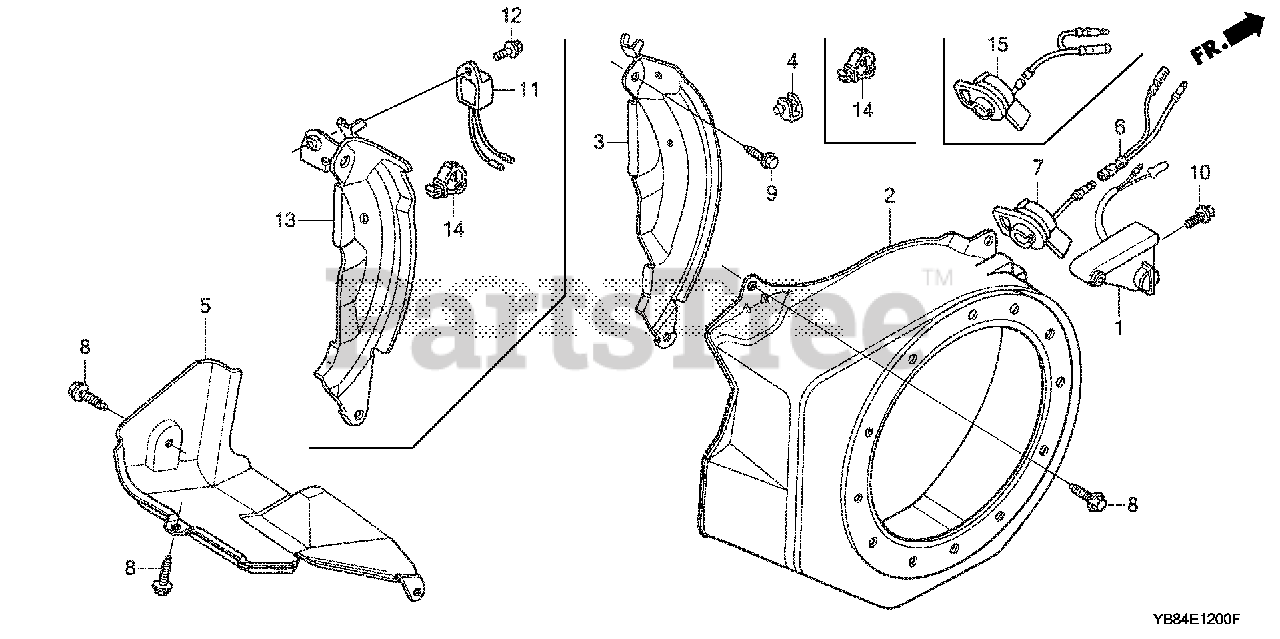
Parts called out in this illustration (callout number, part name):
2	COVER, FAN *R280* (POWER RED)
8	BOLT, FLANGE (6X12) (CT200)
9	BOLT, FLANGE (6X20) (CT200)
11	ALERT UNIT, OIL
12	BOLT, FLANGE (6X8)
13	PLATE, SIDE (OIL ALERT)
14	CLIP, HARNESS
15	SWITCH ASSY., ENGINE STOP (TOYO DENSO)
15	SWITCH ASSY., ENGINE STOP (MINDA)
